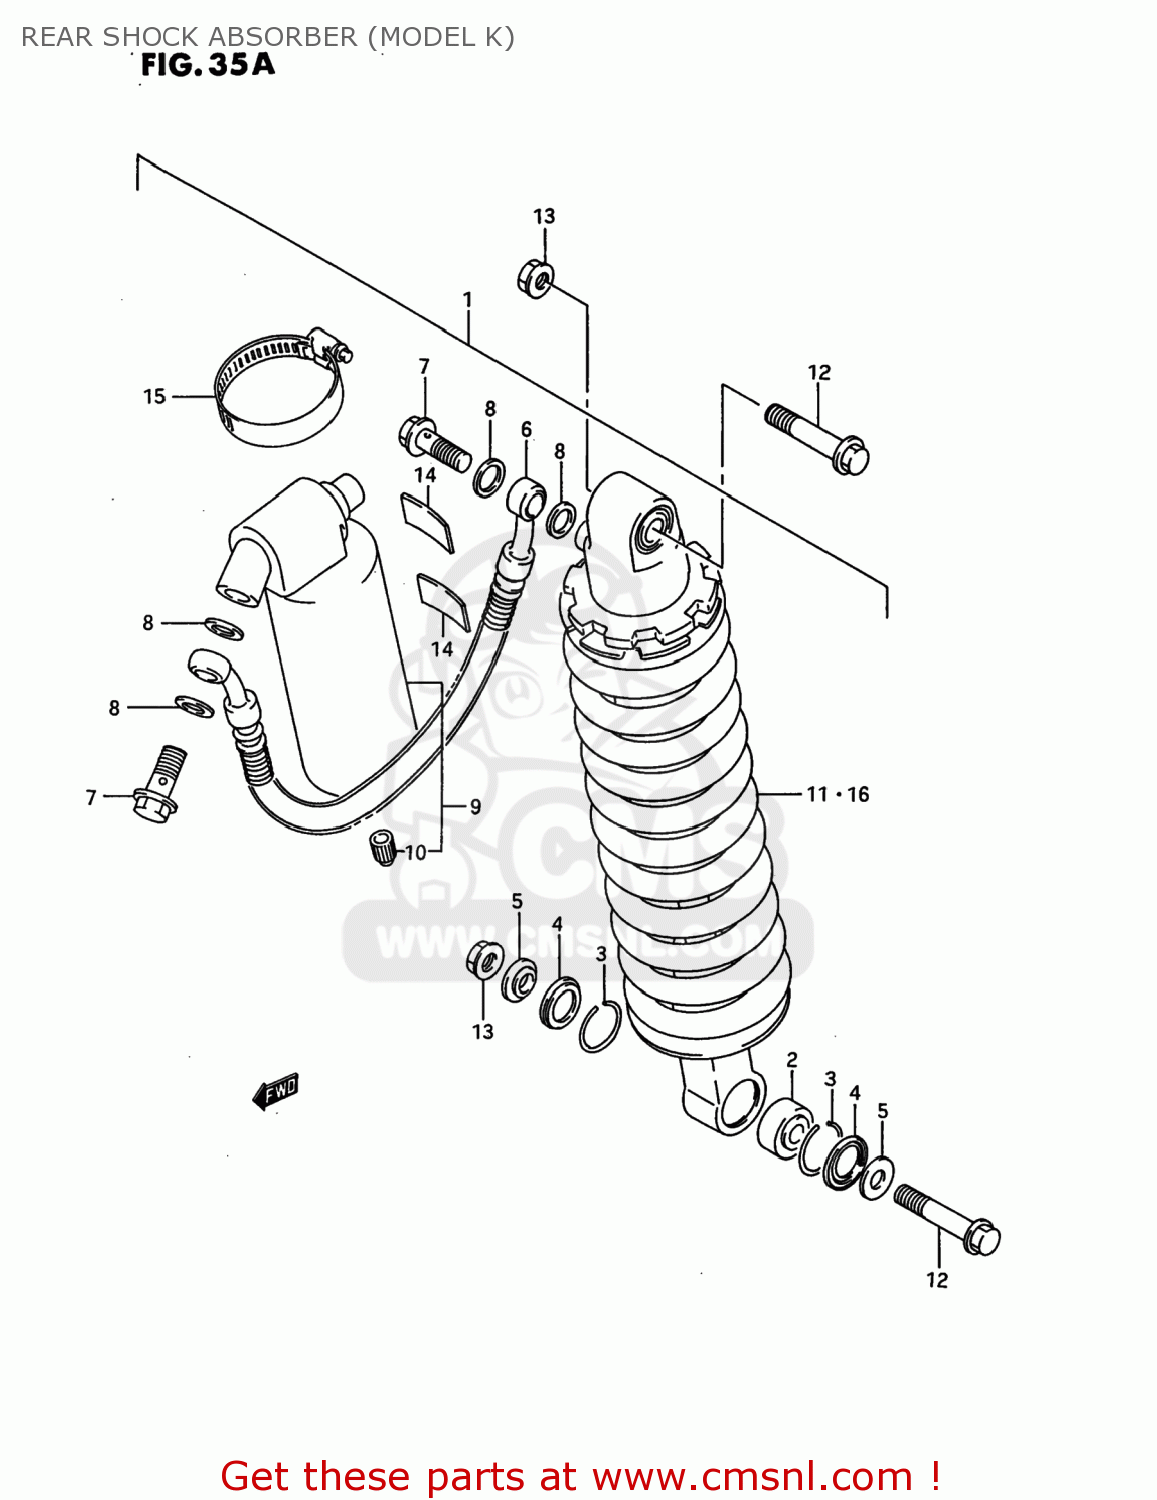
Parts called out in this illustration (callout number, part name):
1	ABSORBER ASSEMBLY,REAR SHOCK
2	BEARING,REAR SHOCK ABSORBER
3	RING
4	DUST SEAL,RR SHOCK
5	COLLAR
6	HOSE,JOINT
7	BOLT,REAR SHOCK ABSORBER
8	WASHER(10X15X1.5)
9	RESERVE TANK,REAR SHOCK
10	CAP
11	SPRING
12	BOLT,RR CUSHION ROD UPR
13	NUT
14	CUSHION,REAR SHOCK ABSORBER
15	CLAMP
16	SPRING (HARD)
